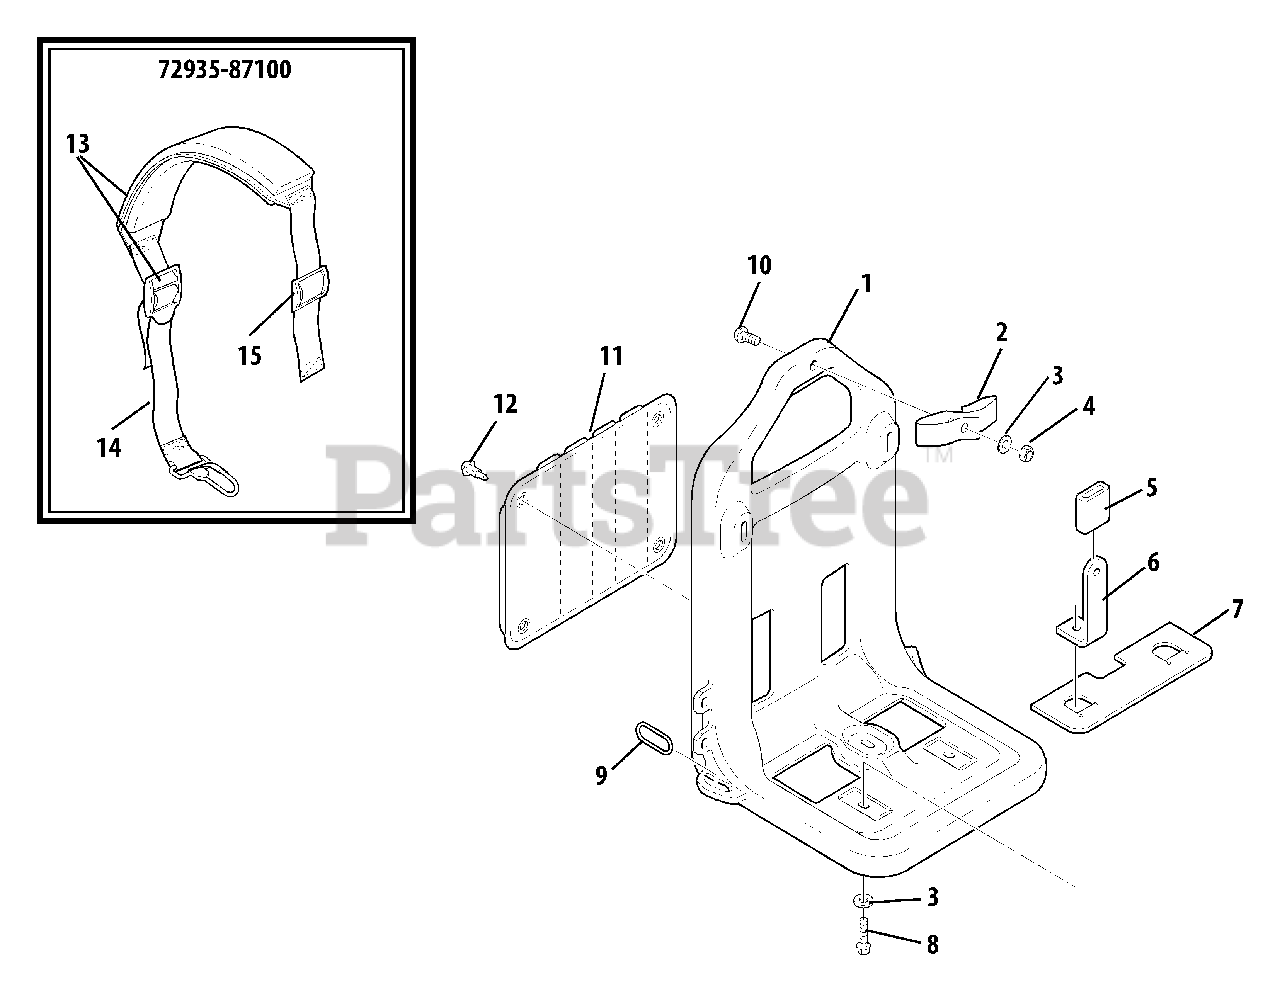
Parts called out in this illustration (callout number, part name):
1	FRAME
2	BAND
4	LOCKNUT - 6
5	CUSHION
6	BRACKET
7	CUSHION
8	SCREW - 6X20
9	HOOK, SPRING
10	SCREW - 6X30
11	PAD
12	CLIP
13	STRAP
14	STRAP
15	BUCKLE
72935-87100	BACKPACK STRAP KIT
